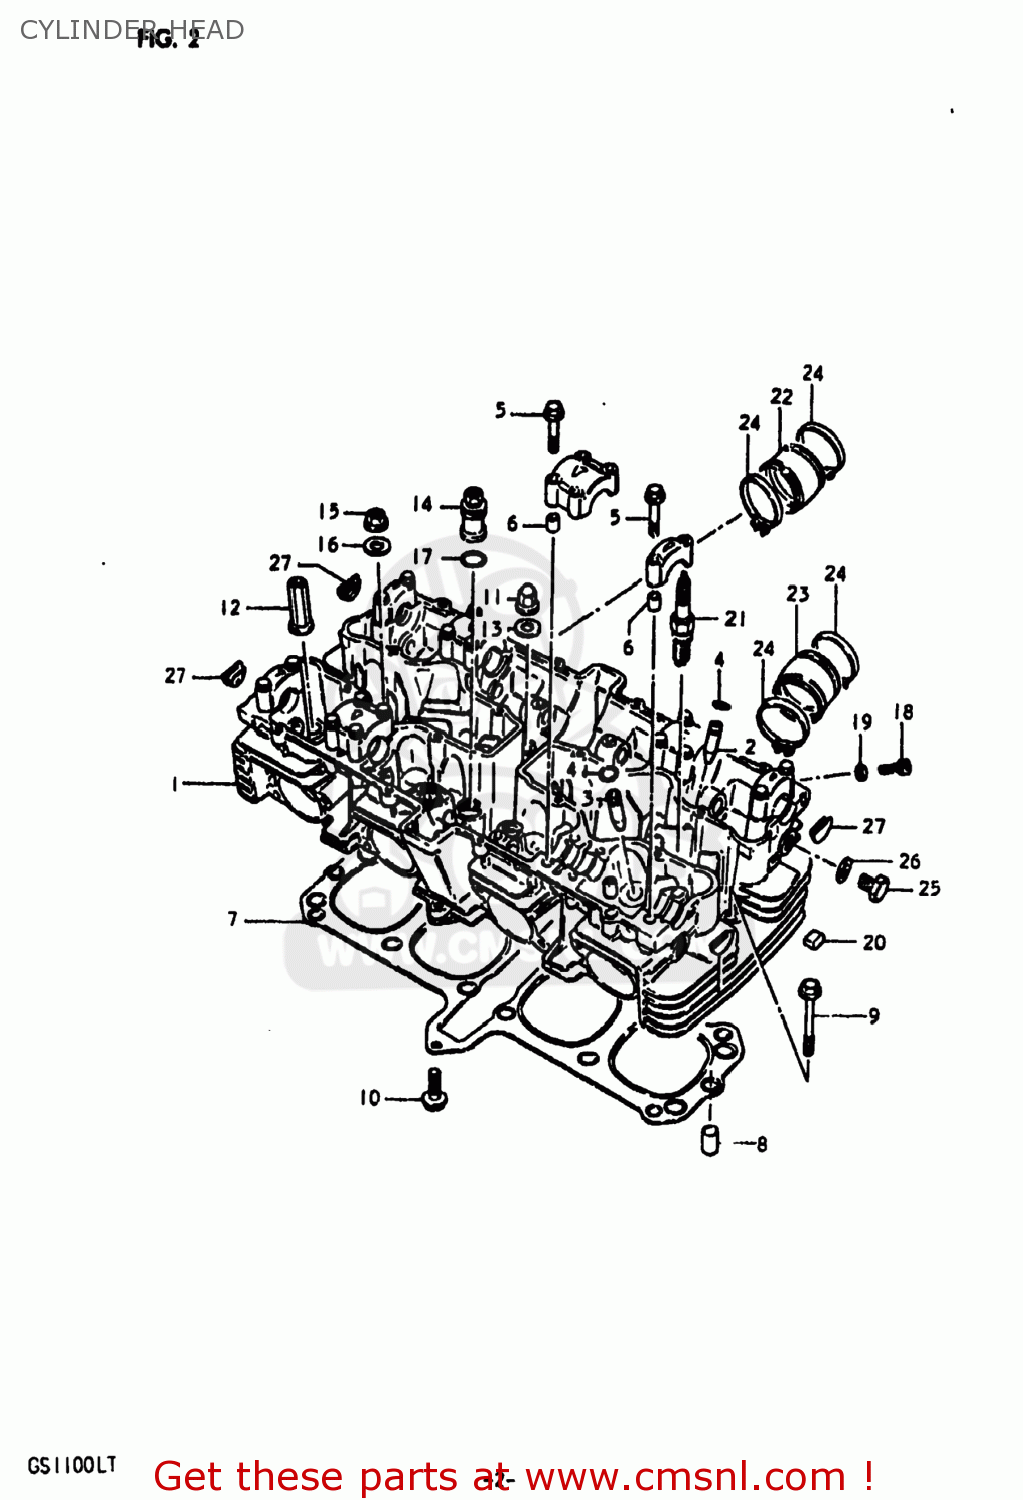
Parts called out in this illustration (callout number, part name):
1	HEAD ASSEMBLY,CYLINDER
2	GUIDE,INTAKE VALVE
3	GUIDE,INTAKE VALVE
4	RING,SNAP
5	BOLT(6X39)
6	PIN(6.2X8X11)
7	GASKET,CYLINDER HEAD (NAS)
8	PIN
9	BOLT
10	BOLT
11	NUT
12	NUT
13	GASKET(10.5X22X2) (NAS)
14	NUT,CYLINDER HEAD SEAL
15	NUT
16	WASHER(10.5X22X2.3)
17	O RING(D:2.4,ID:16.8)
18	BOLT
19	GASKET(5.3X9.3X1.2) (NAS)
20	PAD
21	SPARK PLUG D8EA
22	PIPE,INTAKE,R
23	PIPE,INTAKE,L
24	CLAMP
25	PLUG (14X12)
26	GASKET(14X19.2X2) (NAS)
27	PLUG
